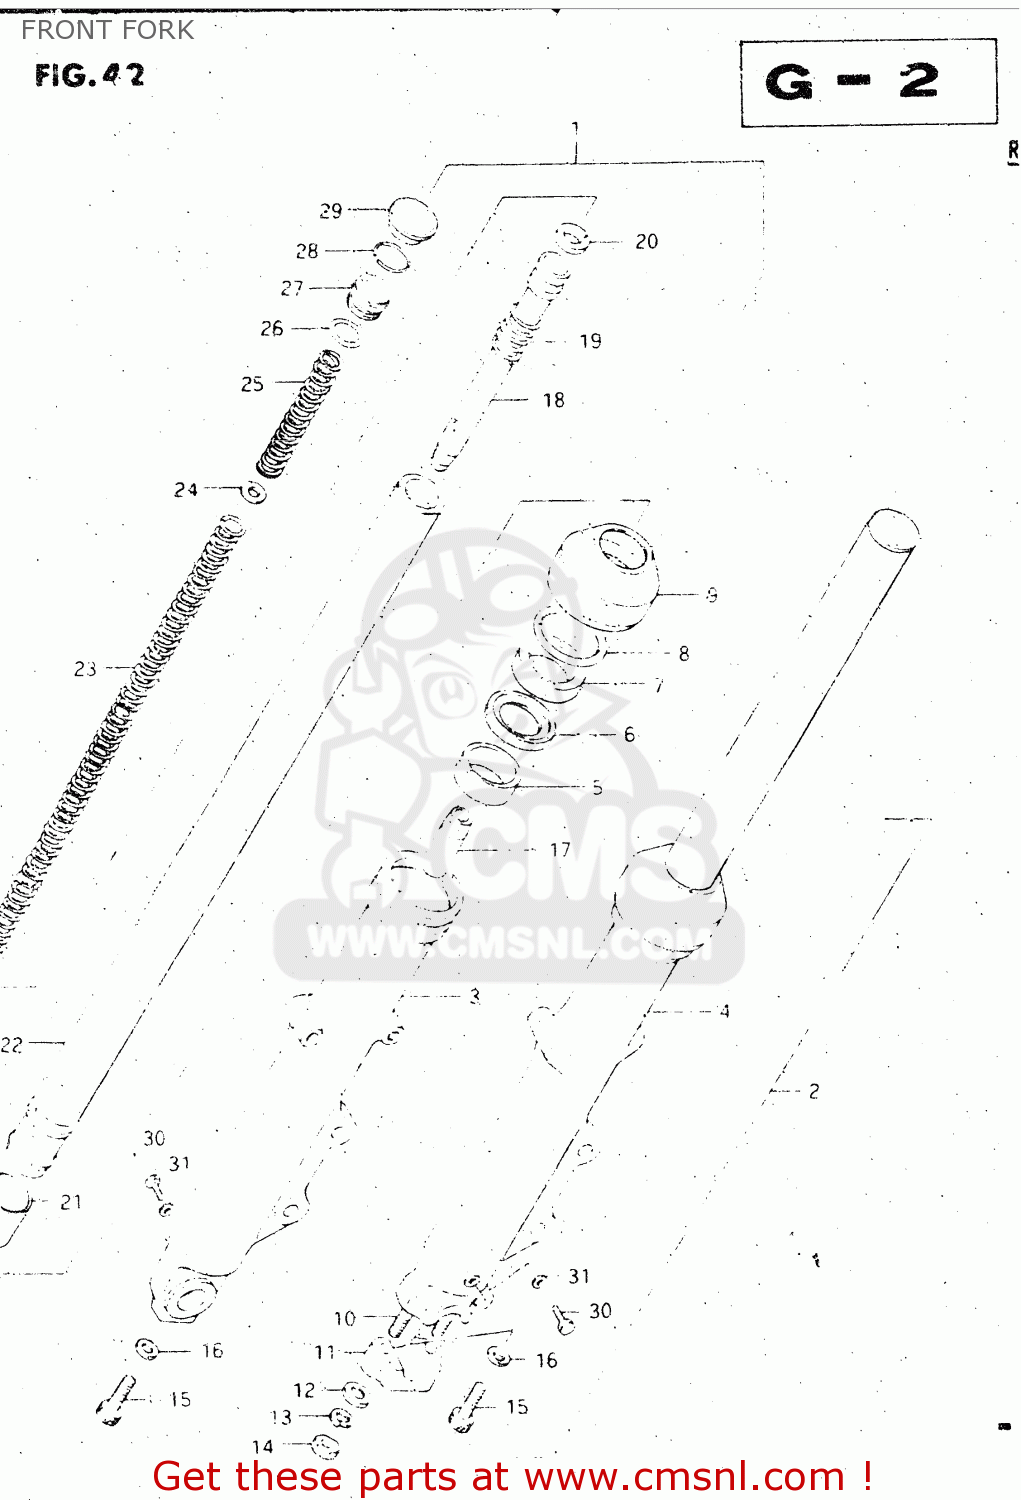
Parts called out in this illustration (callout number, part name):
1	DAMPER ASSY, RH
2	DAMPER ASSY, LH
3	TUBE,FORK,OUTER,RIGHT
4	TUBE,OUTER,LEFT
5	BUSH,GUIDE
6	SPACER,SEAL
7	OIL SEAL,FRONT FORK
8	CIRCLIP,FORK OIL SEAL
9	BOOT
10	STUD 8X25
11	HOLDER,AXLE
12	WASHER
13	LOCK WASHER
14	NUT
15	BOLT(8X27)
16	GASKET (NAS)
17	PIECE,OIL LOCK
18	CYLINDER
19	SPRING,FORK REBOUND
20	RING
21	PISTON
22	TUBE,FORK,INNER
23	SPRING B
24	WASHER,SPRING
25	SPRING A
26	O-RING
27	SPRING SEAT B
28	RING,STOPPER
29	CAP
30	BOLT(6X8)
31	GASKET,DRAIN,PLUG (NAS)
